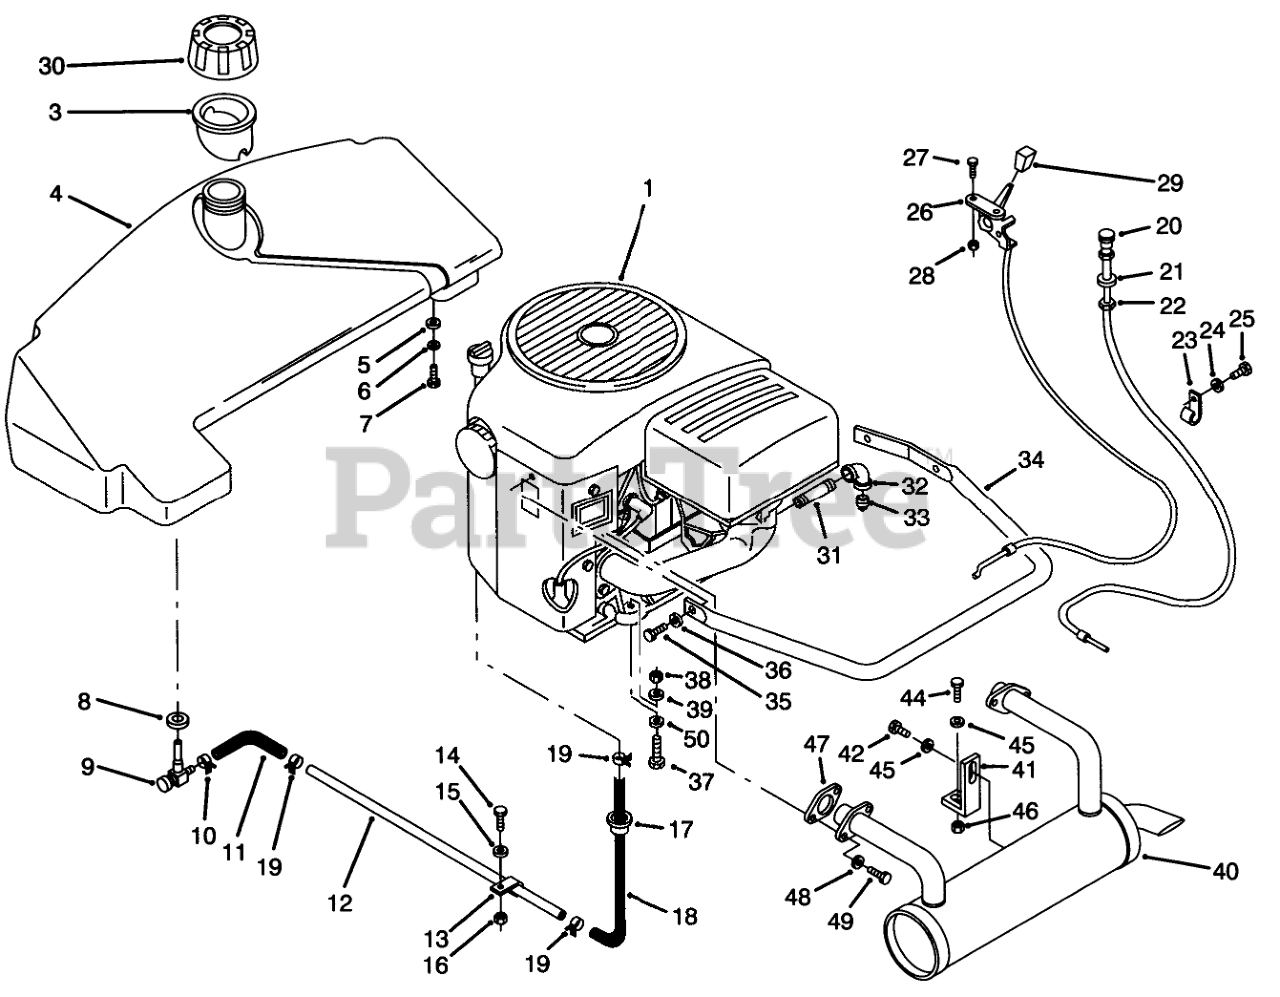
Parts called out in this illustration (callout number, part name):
1	Engine-16HP Model P216V-1/11103-D
3	FUNNEL-FUEL TANK
4	TANK-FUEL ASS'Y
5	Collar
6	Lockwasher
7	Bolt
8	BUSHING
9	VALVE-FUEL
10	Clamp
11	Hose5"
12	TUBE FUEL LINE
13	J-CLIP
14	Bolt
15	WASHER 5/16 SAE
16	Nut
17	BUSHING-NYLON 1.093
18	Fuel Hose 18"
19	CLAMP HOSE .5 IN
20	CONTROL-CHOKE
21	Washer
22	NUT-HEX PALNUT
23	CLIP
24	Washer
25	Bolt
26	CONTROL-THROTTLE
27	Screw
28	Nut
29	KNOB-CONTROL
30	GAS CAP ASM
31	NIPPLE-3/8 X 2.5
32	ELBOW 3/8 90 DEG
33	Plug
34	GUARD-AIR CLEANER
35	H H C S
36	Washer
37	Bolt
38	Nut
39	WASHER 5/16 SAE
40	EXHAUST-MUFFLER
41	BRACKET-MUFFLER
42	H H C S
43	WASHER 5/16 SAE
44	Bolt
45	WASHER 5/16 SAE
46	Nut
47	Exhaust Gasket
48	Lockwasher
49	SHCS 5/16-18X.750
50	WASHER
